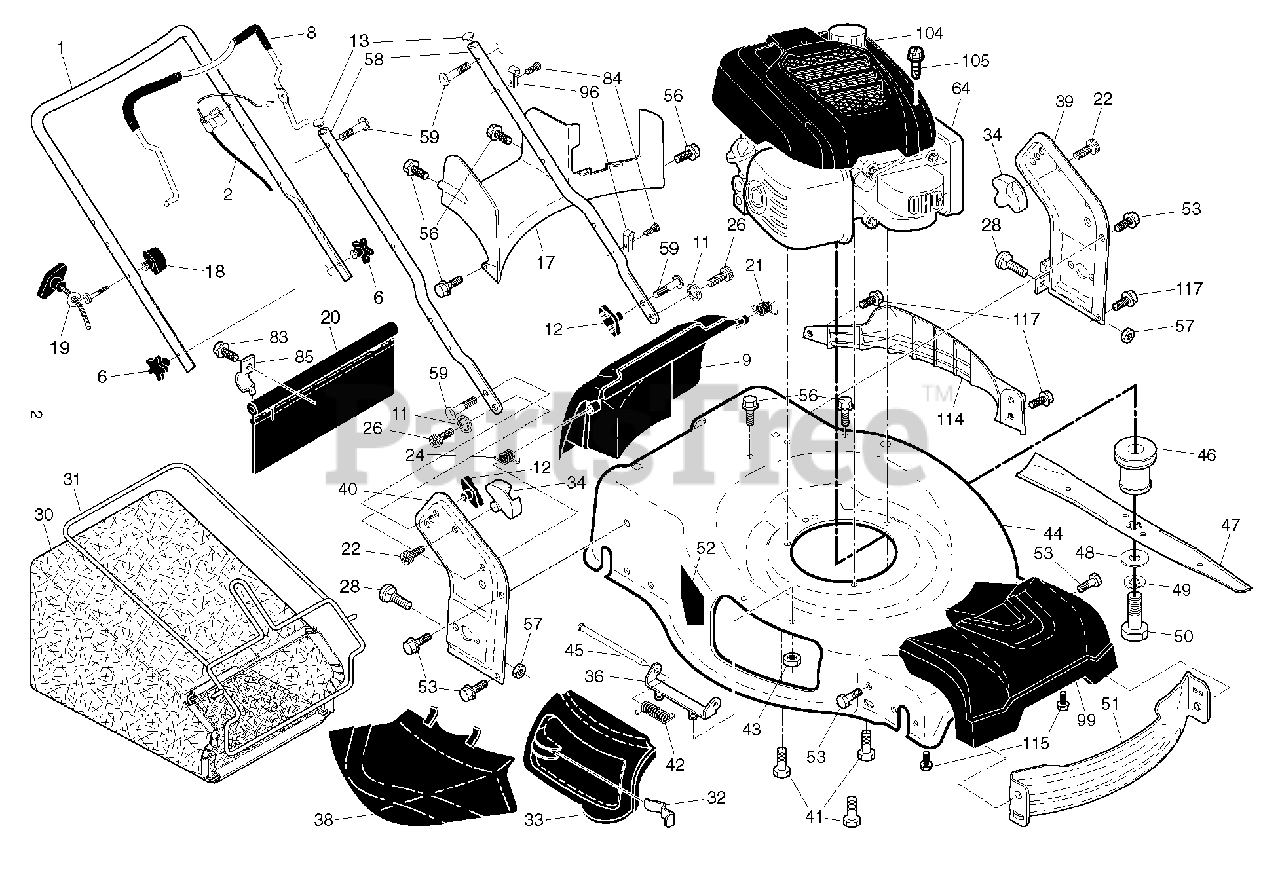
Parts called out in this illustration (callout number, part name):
1	HANDLE.UP.3POS.BS.AW2.GREY
2	CABLE.MZR.ZONE.CONTROL
6	KNOB.HANDLE.PLASTIC.STAR.BLACK
8	BAIL.OM.ERGO.BENT.MZR.ORAN.668
9	DOOR.REAR.ASM.22+.HUSQ.FG/RGD
11	E-RING.12MM.SHAFT
12	KNOB, DEFLECTOR
13	PLUG.PLASTIC.7/8".14-20.GAUGE
17	BAFFLE.REAR.22+RGD.AWD.PLASTIC
18	T-KNOB.NEW ROPE GUIDE
19	GUIDE.ROPE.BLK.ZINC.CHROM
20	SKIRT.REAR.22+RGD.HIGH WHEEL
21	SPRING.LH.BLACK
22	SCREW.PAN.HEAD.#10
24	SPRING.RH.GRAY
26	SCREW,DOOR/HANDLE.PIVOT
28	BOLT.CARRIAGE.LN.5/16-18X.5/8
30	GBAG.BA85028EM.NOFRAME.GRY/SLV
31	FRAME.GBAG.22+.BLK
32	LATCH.DOOR.ZINC
33	DOOR.MULCH.22 PLUS.HUSQ.GREY
34	BRACKET.GRASSBAG.ATTACHING.BLK
36	BRACKET.ASM.HINGE.21.FWGD.
38	DEFLECTOR.CLIPPING.22.BLACK
39	BRACKET.ASM.HANDLE.LT.22+.GREY
40	BRACKET.ASM.HANDLE.RT.22+.GREY
41	BOLT 3/8-16X1-1/8
42	SPRING.TORSION
43	NUT.HEX.FLANGE.1/4
44	KIT.HSG.22+AWD.MC.WO.668.TRI
45	ROD.HINGE.21
46	ADAPTER.BLADE.25MM.3MPH
47	BLADE REAPER, 22 IN RUST
48	WASHER,HARDEN
49	LOCKWASHER
50	SCREW, HEX HD 3/8-24 X 1-3/8
51	BAFFLE.FRONT.22.PLUS
52	DANGER DECAL
53	BOLT.5/16HEX.WHS.HD
56	SCREW.HX.13X.750
57	NUT.FLANGE.5/16
58	HANDLE.LOWER.22+.BT.GRAY
59	BOLT, HANDLE 5/16-18X1.75
83	TAPPING SCREW
84	FASTENER.PUSH.O.250X0.783
85	BRACKET.SKIRT.22+.BZP
96	CLIP.CABLE.BLK
99	COVER.ASSEMBLY.FRONT.22+AWD
104	SHROUD.ASM.HONDA.HUSQVARNA
105	SCREW.SHROUD.HONDA
114	BUMPER.LEFT SIDE 22+.498
115	SCREW.SHOULDER.5/16X1.375
117	BOLT.HEX.HD.WASHER.5/16-18X.75
